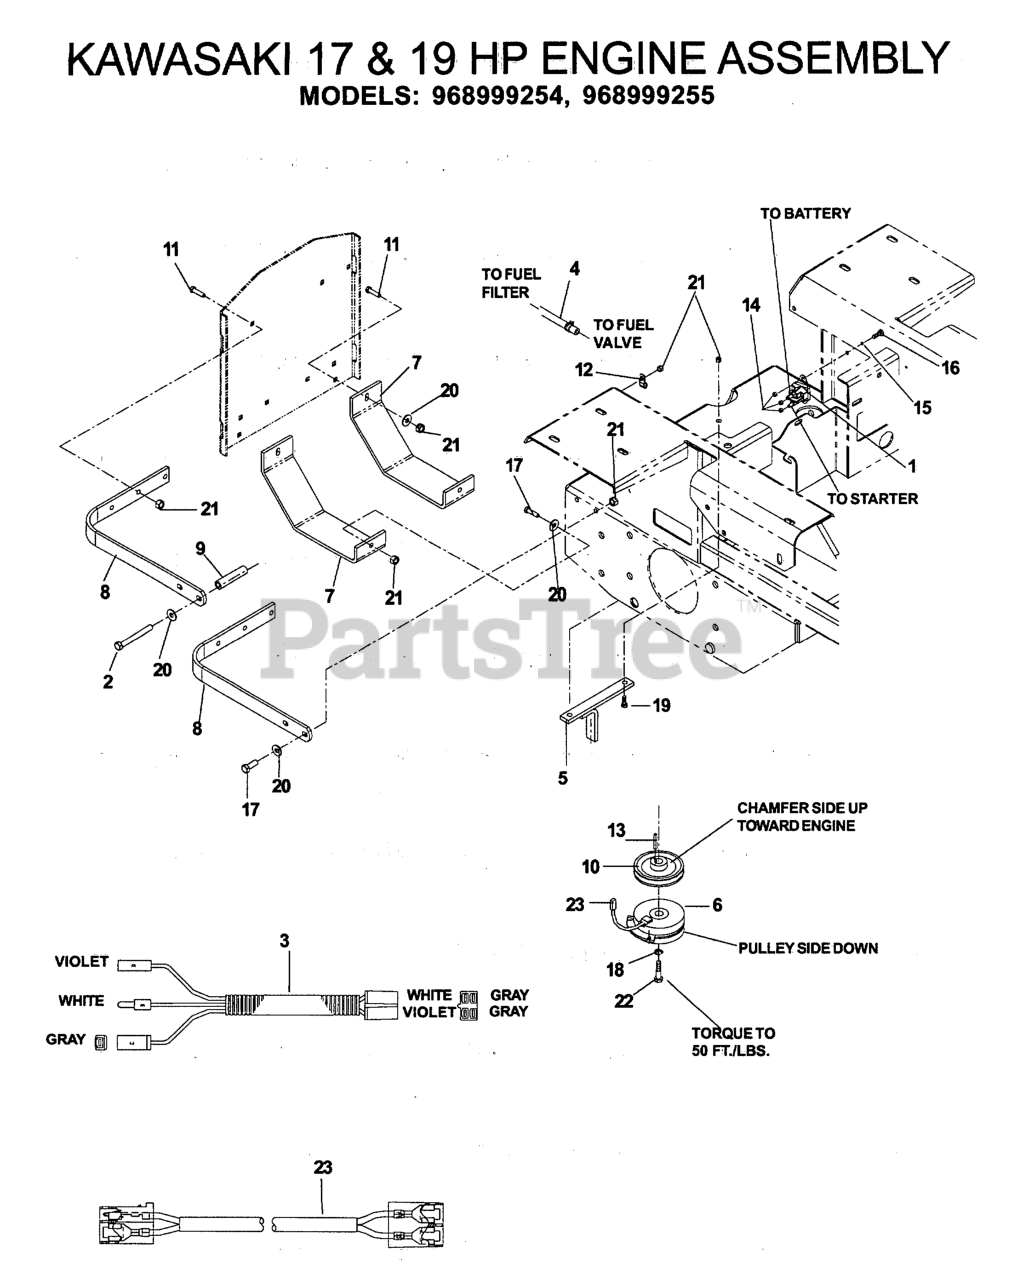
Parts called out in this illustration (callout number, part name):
2	HCS 5/16C X 4
3	KAW PIGTAIL
4	FUEL LINE 29.5"
5	CLUTCH TIE DOWN
7	SKID PLATE
8	ENGINE SHROUD BRKT
11	RHSSNB 5/16C X 1.0
12	DOUBLE TUBE CLAMP
13	KEY, 1/4 SQ X 1 1/4
14	NUT.1/4-20.HEX.NYLOC.ZD
15	WASHER 1/4 INT TOOTH
16	HCS 1/4C X 5/8
17	HCS 5/16C X 1
18	WASHER 7/16 LOCK
19	HCS 5/16C X 1 3/4
20	WASHER 5/16 FLAT
21	NUT 5/16 NYLOC
22	BOLT 7/16F X 2 1/2
23	CLUTCH HARNESS
